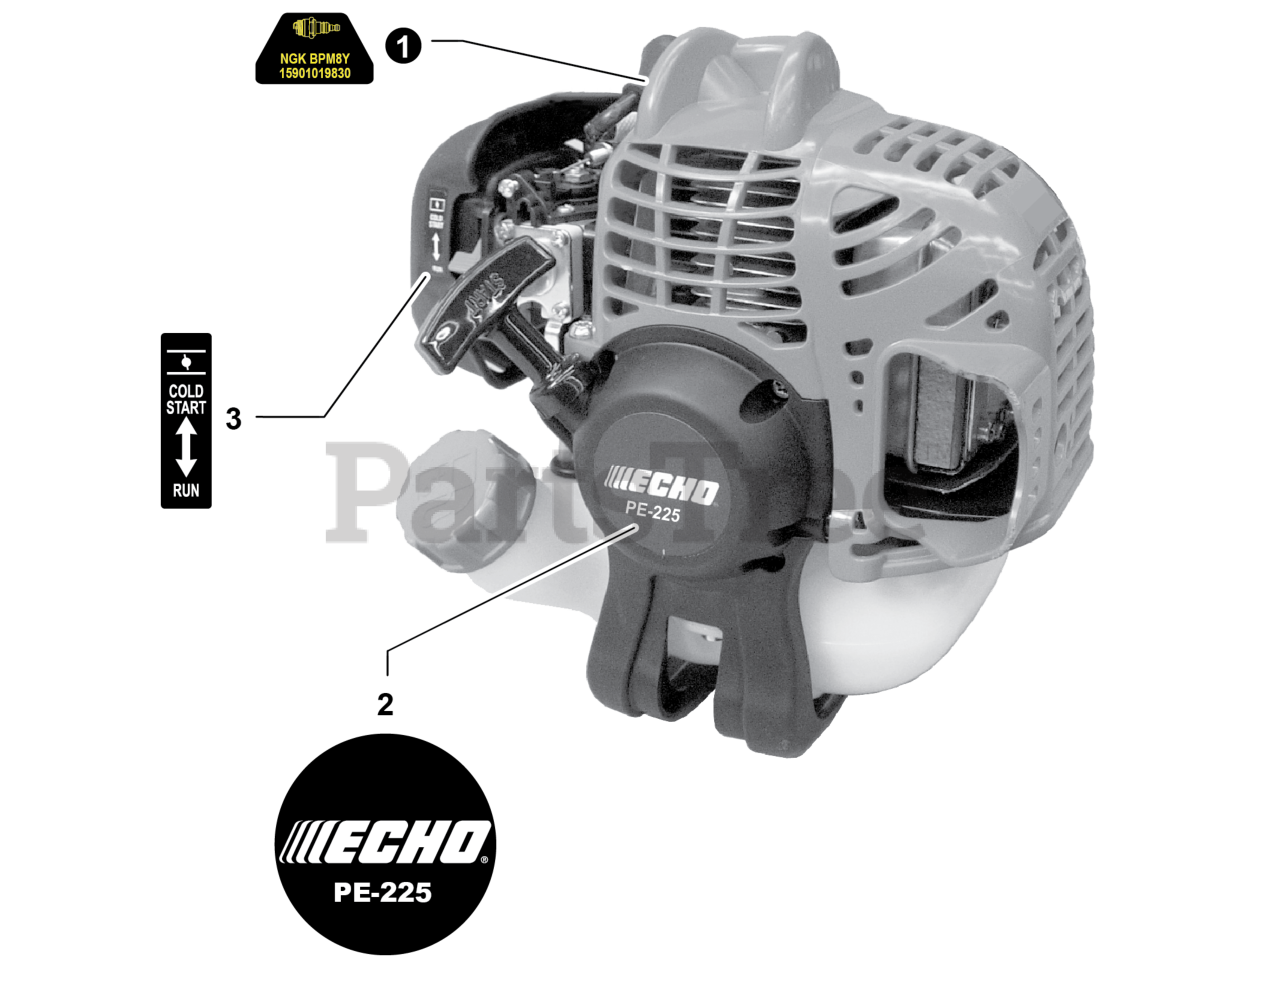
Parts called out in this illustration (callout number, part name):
1	LABEL - SPARK PLUG - BPM8Y
2	LABEL - MODEL - PE-225
3	LABEL - CHOKE
